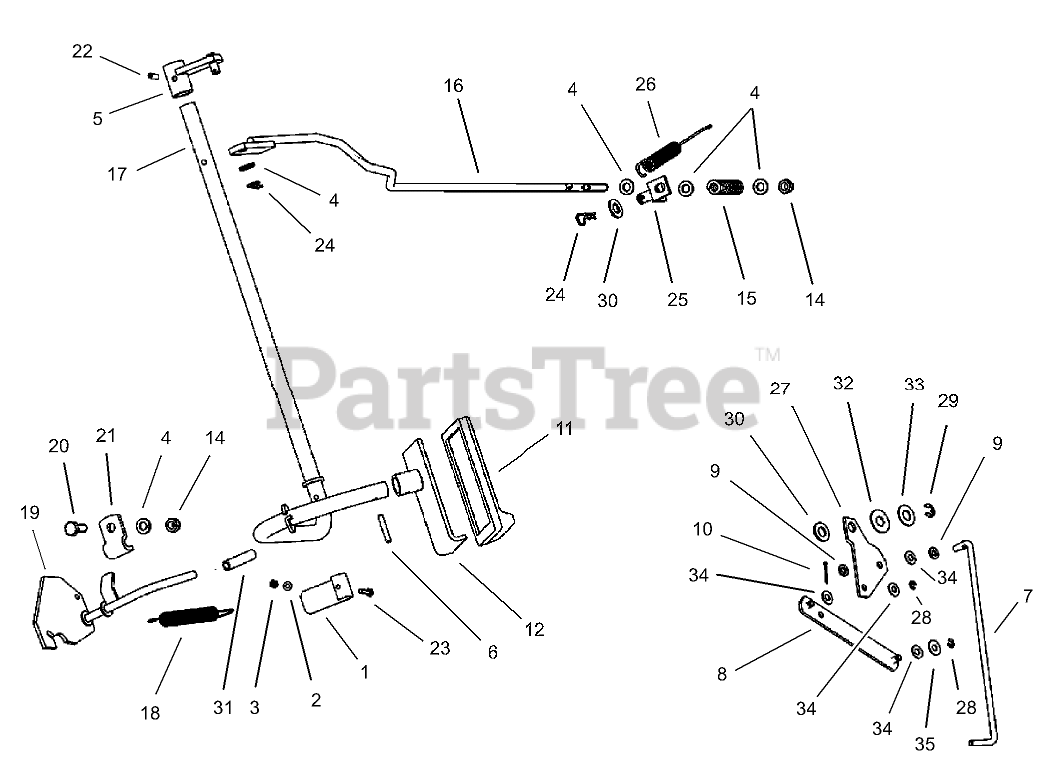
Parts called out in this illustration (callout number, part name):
1	LEVER-SPRING
2	WASHER
3	NUT-HEX
4	WASHER-PLAIN
5	BRACKET-ROD, BRAKE
6	PIN-SPRING
7	ROD-LEVER, BYPASS
8	Lever-Bypass
9	WASHER
10	PIN-COTTER
11	PAD-PEDAL
14	NUT-LOCK, NI
15	SPRING-BRAKE
16	ROD-CONNECTING, BRAKE
17	SHAFT-BRAKE
18	SPRING-BRAKE, HAND
19	LEVER-BRAKE, HAND
20	SCREW-HH
21	CLAMP-LEVER, PARKING BRAKE
22	PIN-SPRING
23	SCREW-HEX
24	PIN-COTTER
25	BRACKET-ROD, BRAKE
26	SPRING
27	Plate-Bypass
28	STIRRUP
29	E-CLIP
30	WASHER-FLAT
32	Washer
33	Washer
34	Washer
35	Washer
